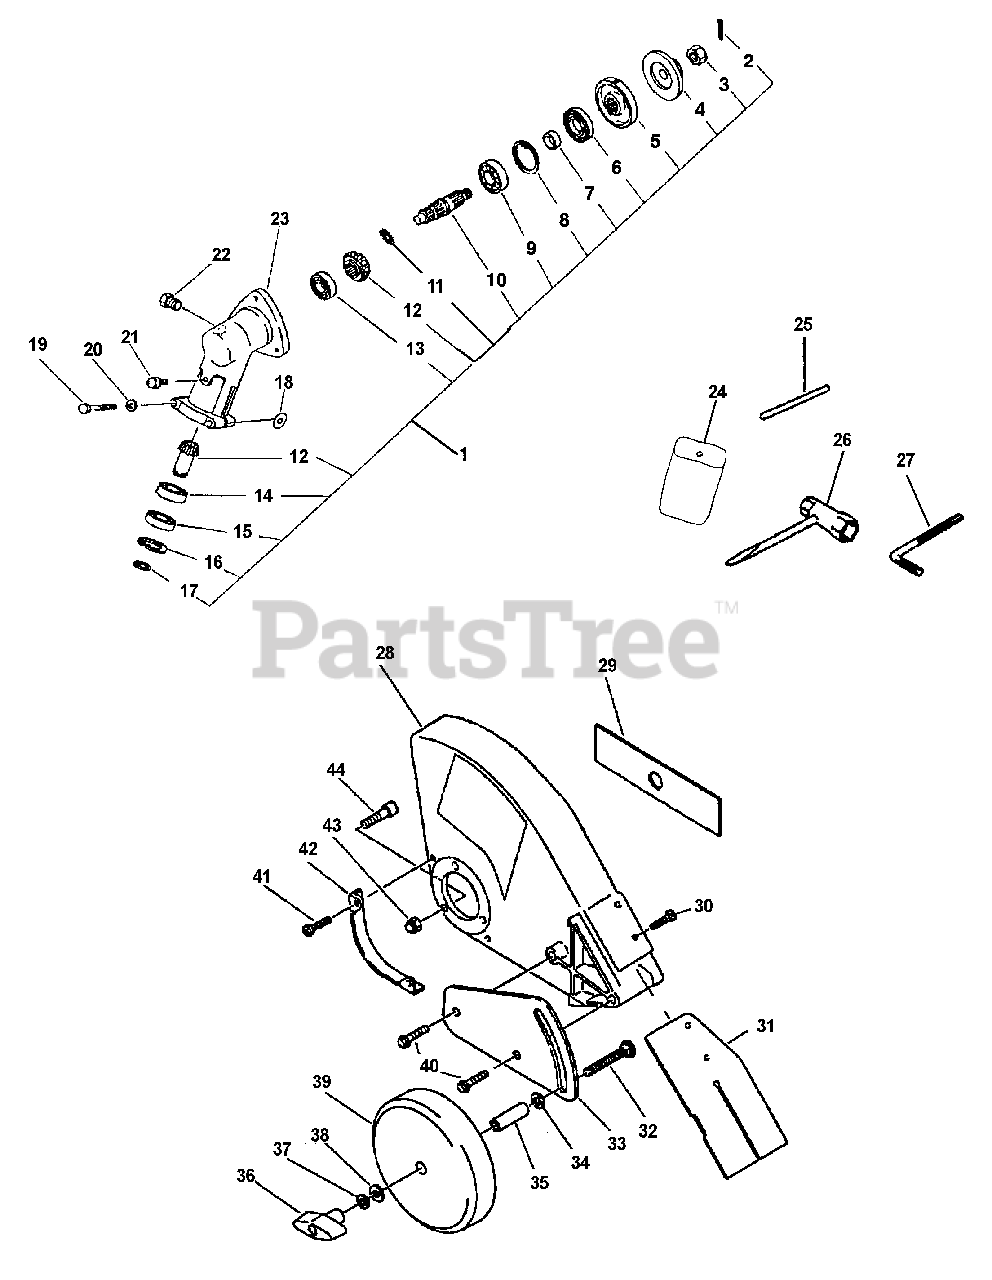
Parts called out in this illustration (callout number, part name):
1	GEAR CASE ASSY
2	PIN, SPLIT - 2X22
3	LOCKNUT - LEFT HAND
4	ADAPTOR, BLADE - LOWER
5	ADAPTOR, BLADE - UPPER
6	SEAL, OIL
8	RING, RETAINING - 32
9	BEARING, BALL - 6201
10	GEAR - SHAFT
11	RING, RETAINING - 10
12	GEAR SET - BEVEL
13	BEARING, BALL - 609
14	BEARING, BALL - 6900
15	BEARING, BALL - 6900Z
16	RING, RETAINING - 22
17	RING, RETAINING - 12
19	BOLT - 5X30
20	WASHER - 5
21	BOLT - 8X6
22	SCREW - 5X10
23	CASE, GEAR
24	BAG, TOOL
25	LOCKING TOOL
26	T-WRENCH - 17X19mm
27	HEX KEY - 4mm
28	SHIELD, DEBRIS
29	BLADE, EDGER
30	SCREW - 3
31	FLAP, DEBRIS
32	BOLT - CARRIAGE
33	BRACKET, WHEEL
34	WASHER - 10
35	COLLAR - 12
36	WINGNUT - 5/16-18
37	LOCKWASHER - 8
38	WASHER - 8
39	WHEEL - 6X1.5
40	BOLT - 8
41	SCREW - 4X16
43	LOCKNUT - 5
44	SCREW - 5X22
